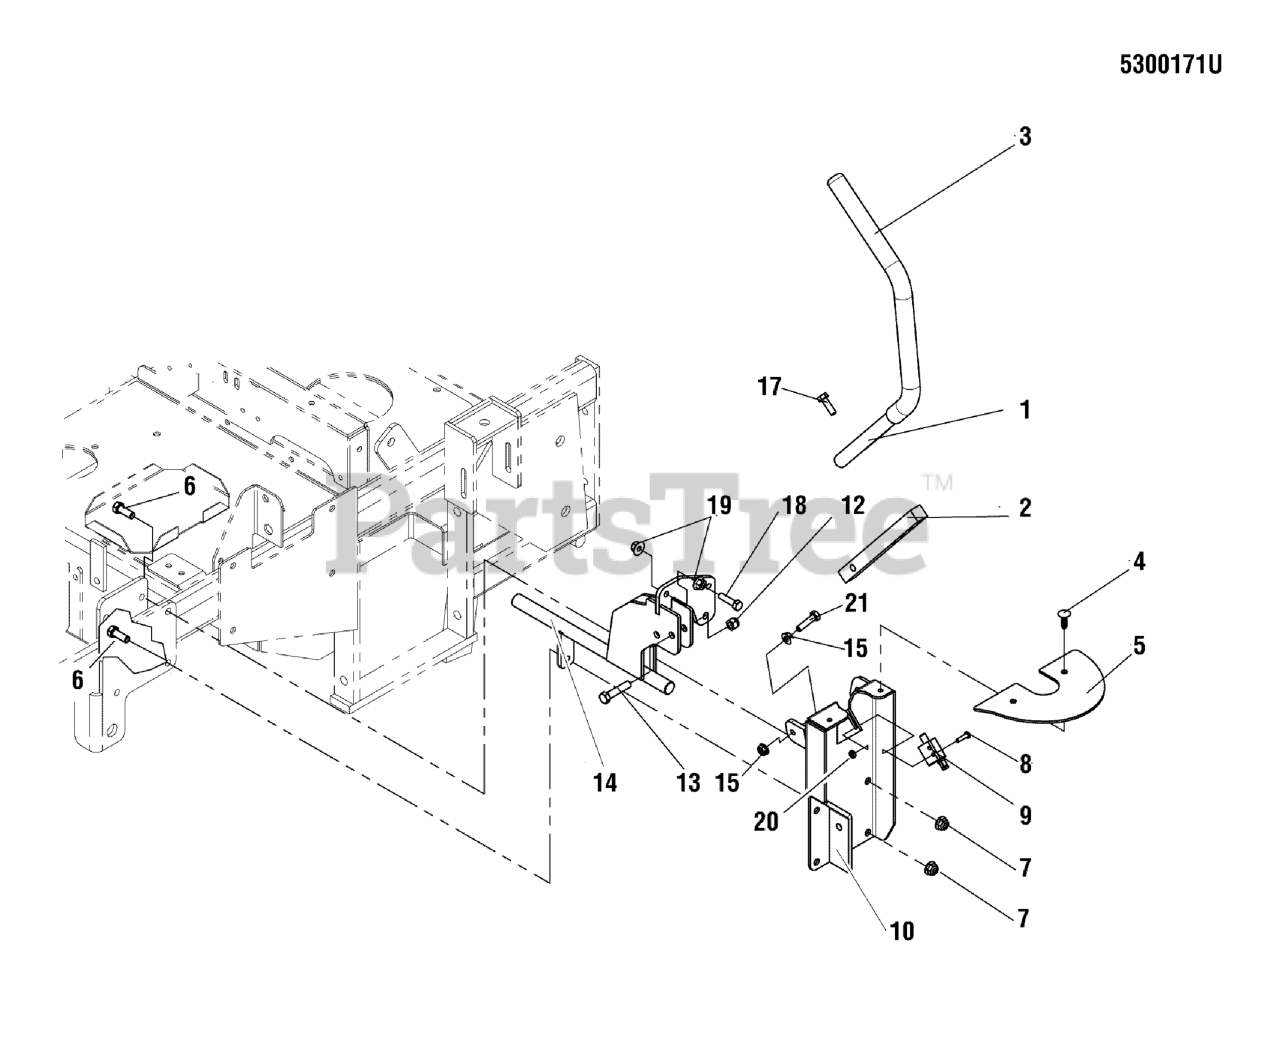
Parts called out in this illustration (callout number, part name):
1	WELD, MOTION CONTROL HANDLE, LH - BLK
2	MOUNT, CONTROL ARM - BLK
3	GRIP, FOAM, 3/4" ID, 16" LONG
4	PUSH RIVET (TREE TYPE) BLACK
5	RUBBER FLAP, CONTROLS
6	BOLT, 3/8-16 X 1" GD5 CZ
7	NUT, 3/8-16 HEX NYLOCK FLANGE
8	SCREW, #10-24 X 1/2"
9	SWITCH PLUNGER N.O.
10	WELD, NEUTRAL LOCK, LH - BLK
12	NUT, 3/8-16 HEX NYLOCK FLANGE
13	BOLT, 3/8-16 X 1-3/4" GD5 CZ
14	WELD, CONTROL SHAFT, LH 3000 - BLK
15	NUT, 5/16-18 HEX SERRATED FLANGE (SMALL)
17	SCREW, 5/16-18x0.750, GR5, WHIZ-LOCK, ZC
18	BOLT, 5/16-18 X 1-1/4" GD5
19	NUT, 5/16-18 HEX SERRATED FLANGE (LARGE)
20	10-24 HEX NUT
21	5/16-18 X 1-3/4, TFL
